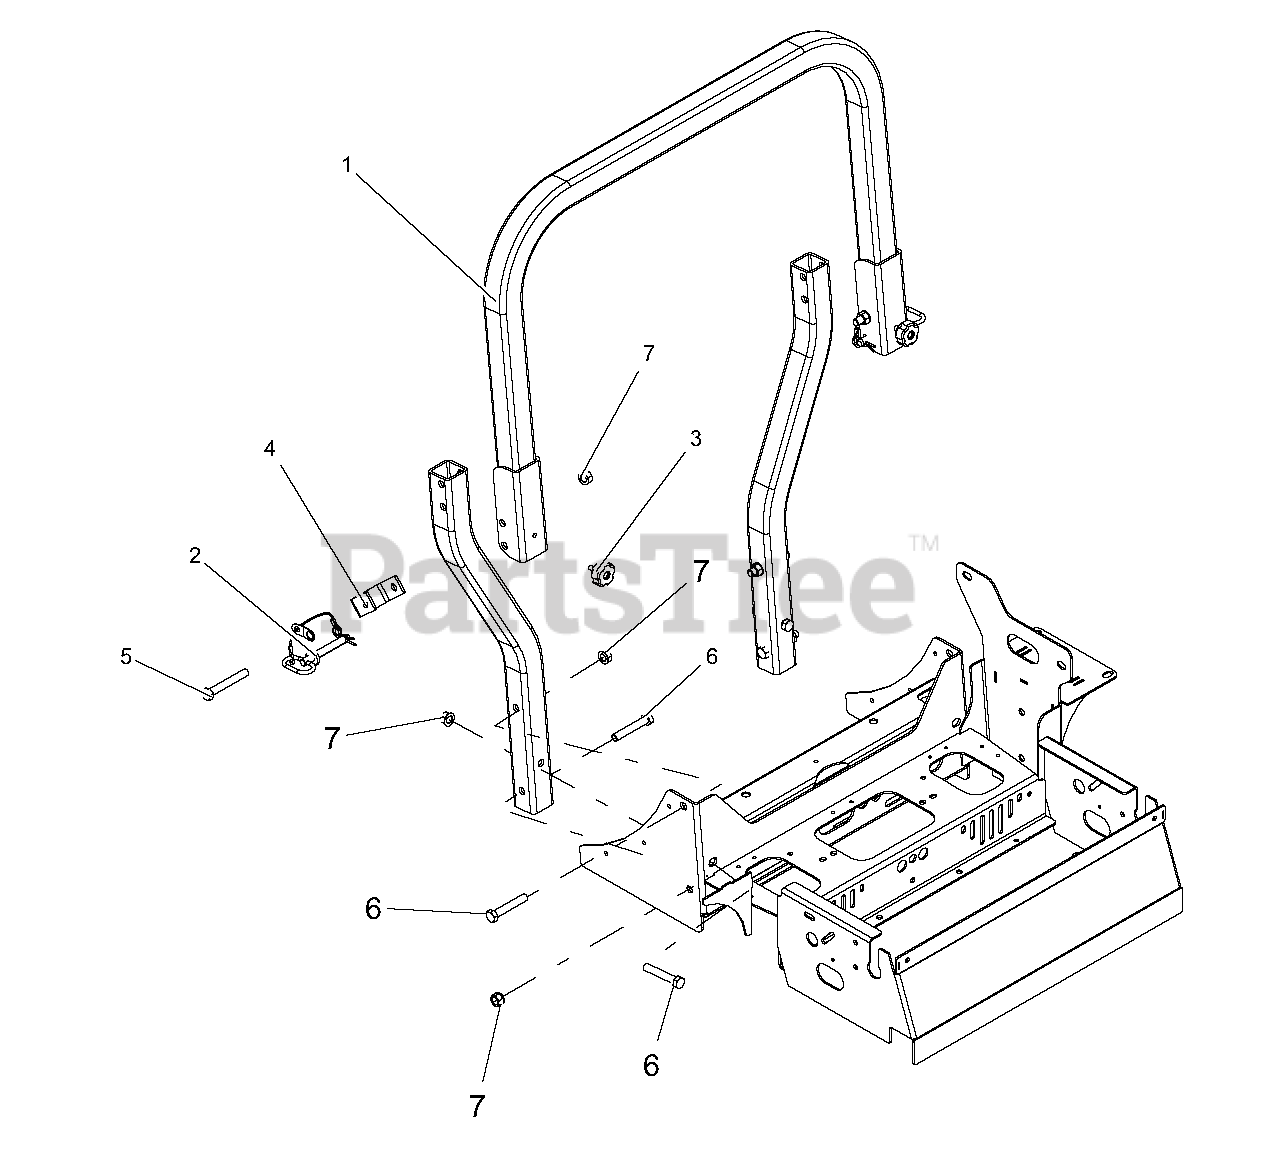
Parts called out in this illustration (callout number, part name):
1	ROPS INCLUDES HOOP RH AND LH SUPPORT
2	ASSY, ROPS PIN/LANYARD
3	KNOB, ROUND 5/16-18 X .750
4	BRKT, ROPS STOP
5	BLT-HEX .50-13X3.50 GR5 YWZC
6	BLT-HEX .50-13X3.00 GR5 YWZC
7	@NUT, LK-TOP-FLG .50-13 YWZC
